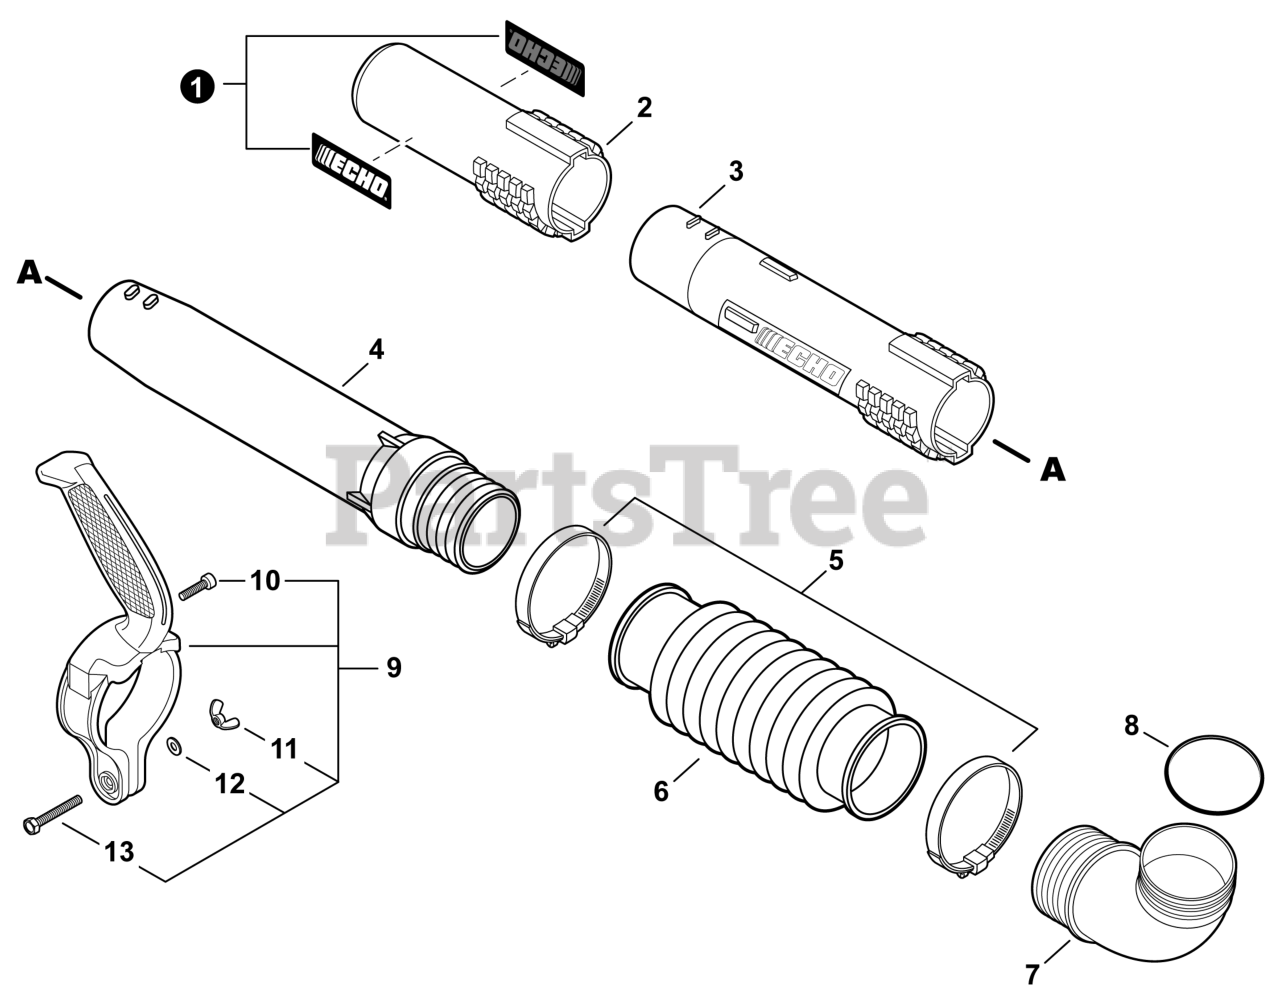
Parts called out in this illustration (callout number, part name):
1	LABEL - ECHO
2	TUBE, BLOWER - NOZZLE
3	TUBE, BLOWER - STRAIGHT
4	TUBE, BLOWER - SWIVEL
5	CLAMP - BAND 78 MM / 103 MM
6	TUBE, BLOWER - FLEXIBLE
7	TUBE, BLOWER - ELBOW
9	HANDLE KIT - BLOWER TUBE
10	BOLT, TORX 4x16
11	NUT, WING 6
12	WASHER 6.5x11.5x0.8
13	BOLT 6x25
